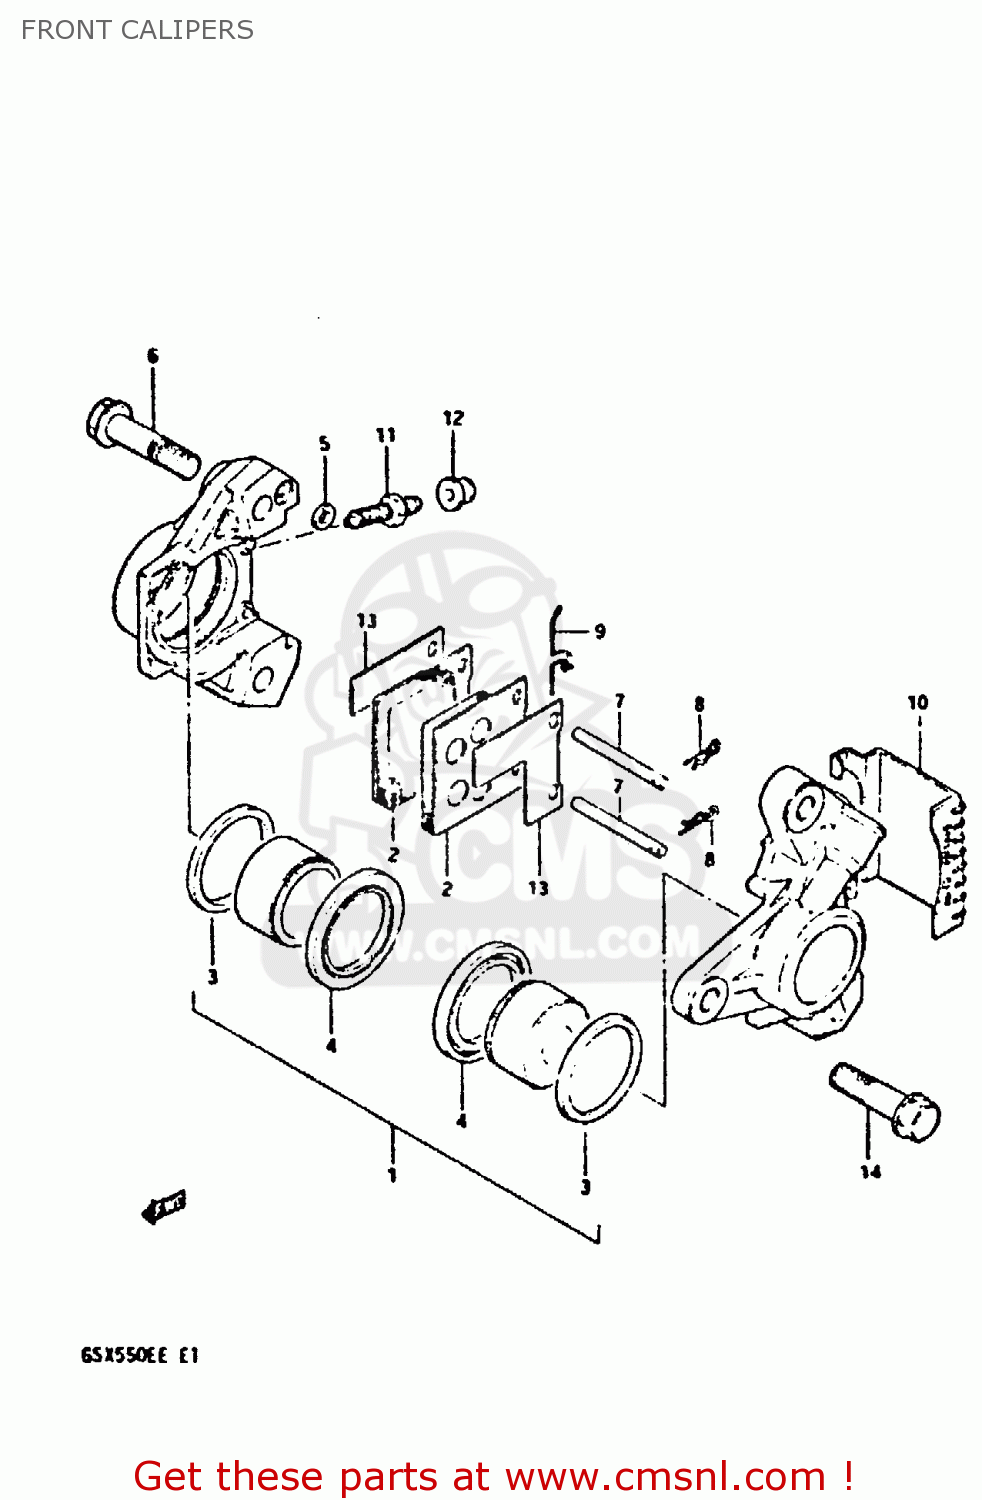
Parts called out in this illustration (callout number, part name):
1	PISTON SET
2	PAD (MCA)
3	SEAL,PISTON
4	BOOT
5	SEAL,JOINT
6	BOLT,HOUSING
7	PIN,PAD
8	CLIP,PAD PIN
9	SPRING
10	COVER,CALIPER
11	BLEEDER
12	CAP,BREATHER
13	SHIM
14	BOLT 10X37
